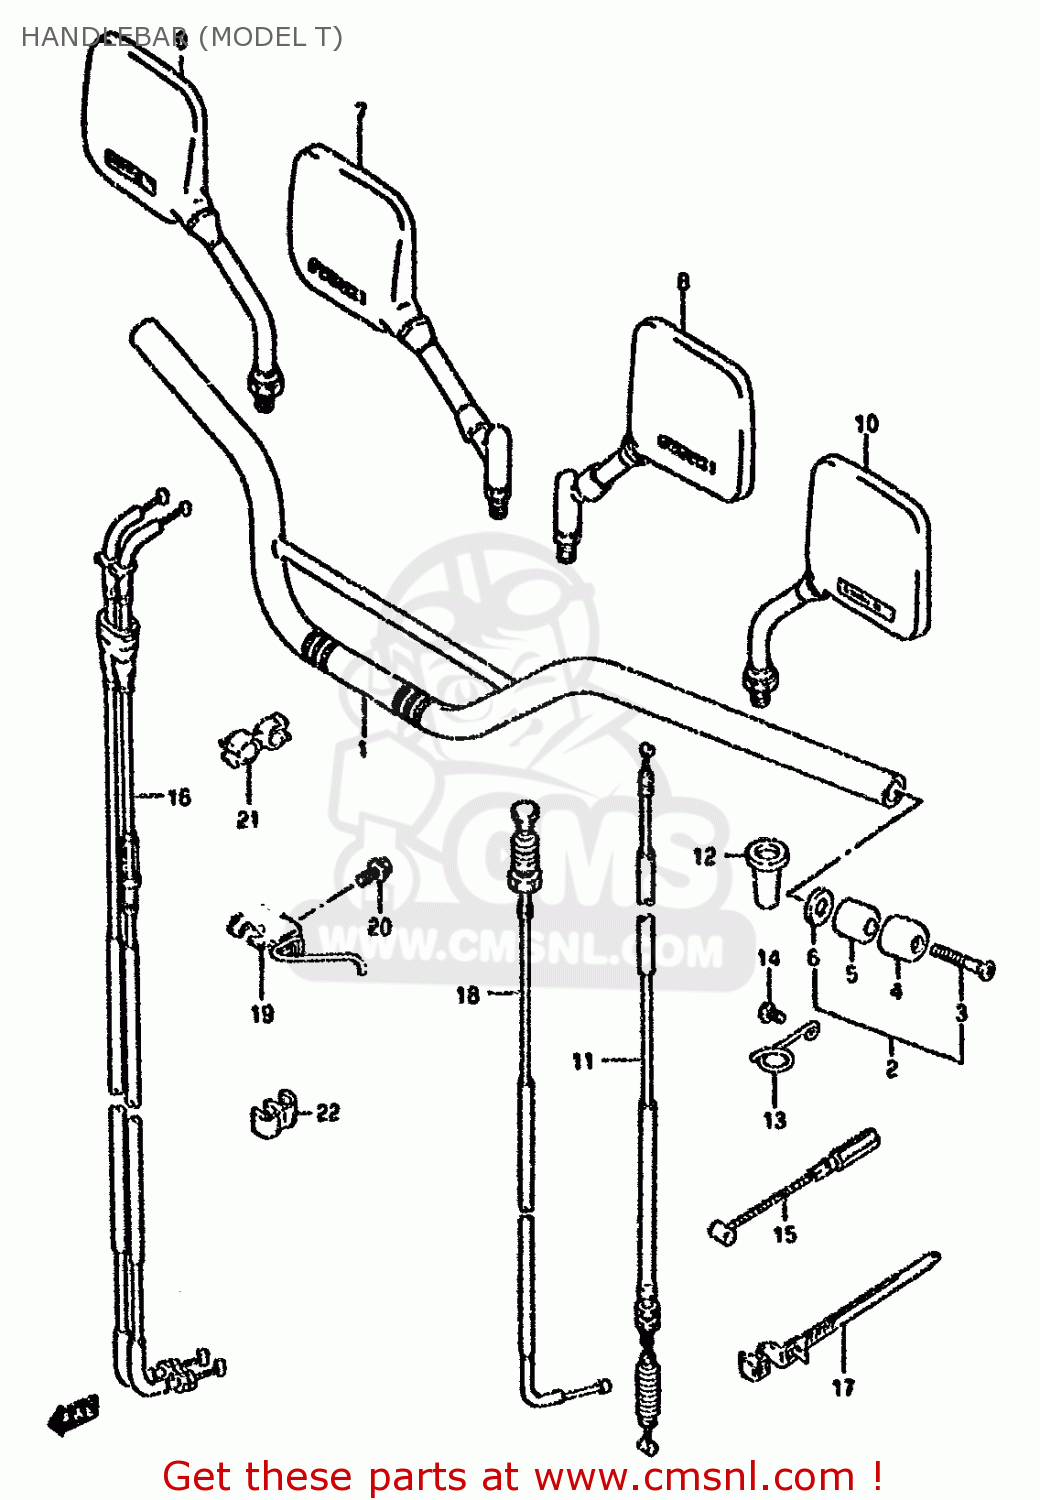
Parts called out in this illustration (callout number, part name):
1	HANDLEBAR
2	BALANCER SET,HANDLEBAR
3	SCREW
4	CAP,BALANCER
5	BALANCER,HANDLE
6	SPACER,BALANCER
7	MIRROR ASSY
8	MIRROR ASSY, L
9	MIRROR ASSY,RH
10	MIRROR ASSY,RE
11	CABLE ASSY,CLUTCH
12	BOOT,CLUTCH CABLE
13	GUIDE,CLUTCH CABLE
14	SCREW 6X12
15	CABLE ASSY,DECOMP
16	CABLE ASSY,THROTTLE
17	CLAMP, CABLE
18	CABLE ,STARTER
19	CABLE ,STARTER
20	BOLT
21	BOLT
22	CLIP
23	CLIP
